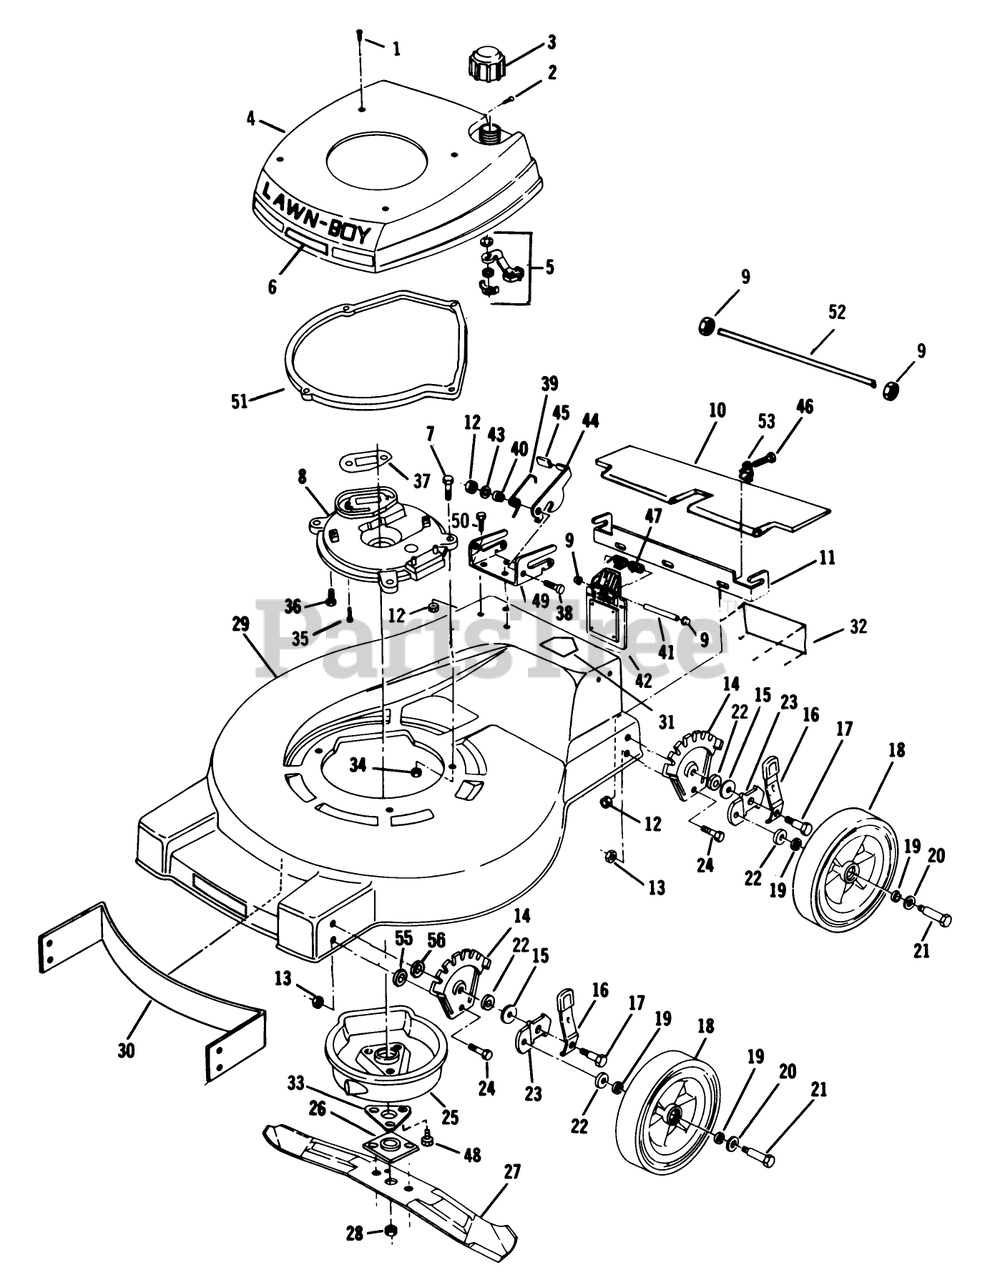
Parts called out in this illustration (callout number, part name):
1	SCREW LAWRENCE
2	SCREW S
3	FUEL CAP & INSERT
7	SCREW-HH
8	PLATE,MUFFLER F
10	T/SHIELD SM&P
12	LOCKNUT E
13	LOCKNUT
15	WASHER
16	KNOB&SPRING FORMCO
17	BOLT
19	WASHER
20	SPACER
21	BOLT WHEEL
22	WASHER WROUGHT
26	PLATE AND COLLAR ASM
28	NUT-BLADE
33	SUPPORT F
34	NUT-LOCK F
35	SCREW V
39	SPRING
41	ROD ROCK/HDWE
45	KNOB (S&R)
47	SPRING ASOC
48	SCREW
55	WASHER
56	WASHER
